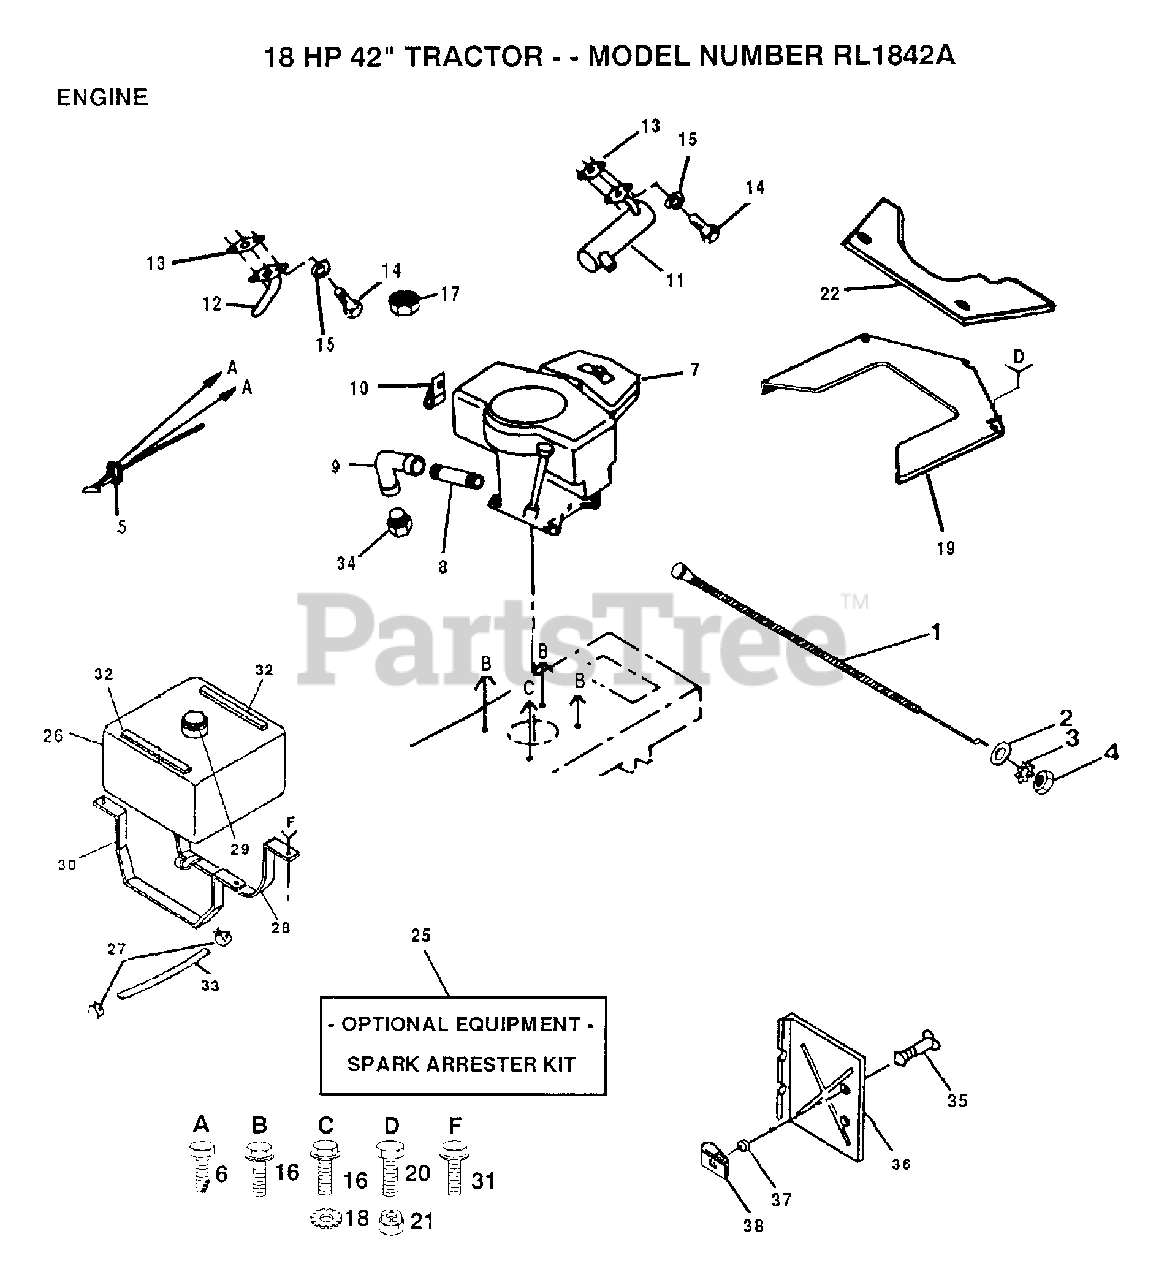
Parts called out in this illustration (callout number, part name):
1	CHOKE CONTROL
2	WASHER
3	LOCKWASHER
6	SCREW LT
7	ENGINE B&S 18HP
8	PIPE NIPPLE LT
9	ELBOW
10	CLIP T
12	EXHAUST TUBE T
15	LOCKWASHER
16	SCREW LT
17	NUT
18	LOCKWASHER
19	SHIELD HEAT FRT
22	REAR BAFFLE T
25	SPARK ARREST KIT
27	HOSE CLAMP
28	STRAP ASM. F.TANK
30	"STRAP,TANK"
31	SCREW LT
32	"STRIP,FORM"
35	STUD.1/4.TURN
36	HEAT SHIELD
37	RETAINER LT
38	RECEPTACLE LT
